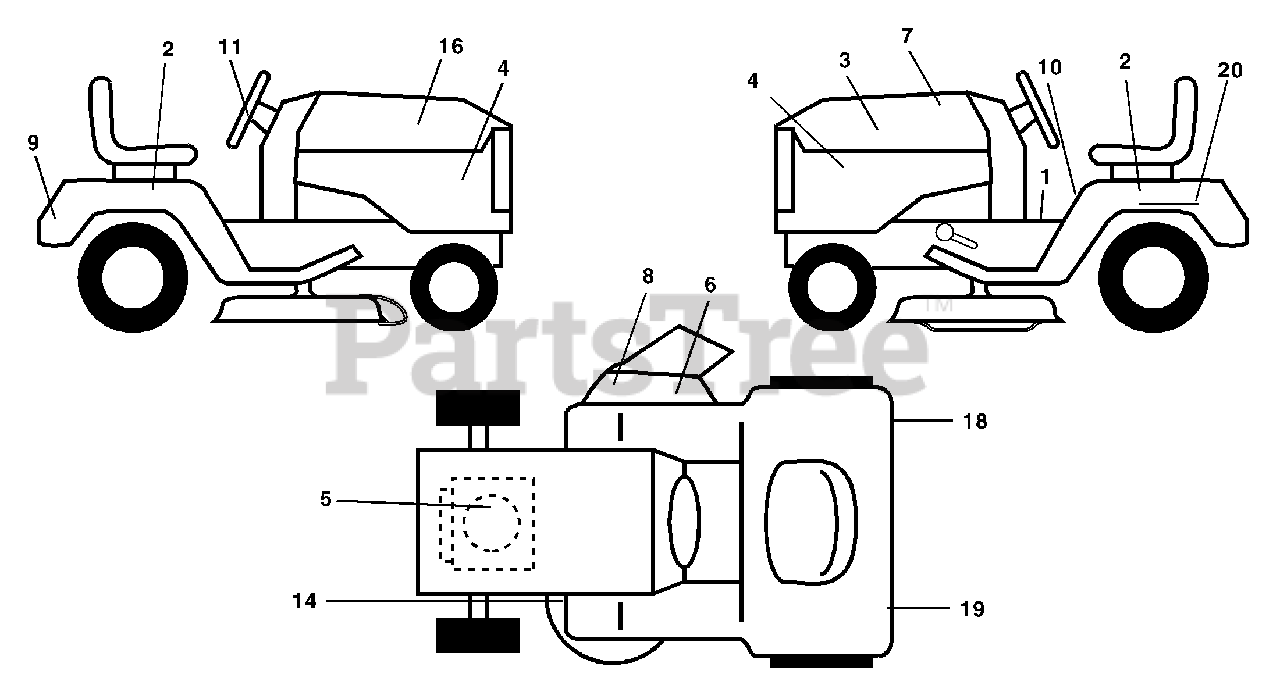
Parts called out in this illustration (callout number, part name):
1	Decal Oper
2	Decal Fender Side
3	Decal Hood LH
4	Decal Side Panel Logo
5	Decal HP Engine
6	Decal Deck "B" 42"
7	Decal Repl. Parts
8	Decal Warning Mult-Language
9	Decal Fender Logo
10	Decal Fender Danger E/F
11	Decal Ins Strg Whl
14	Decal V-Belt Schematic
16	Decal Hood Rh
18	Decal Fender Reflector RH
19	Decal Fender Reflector LH
20	Decal Bat Dan/Psn
